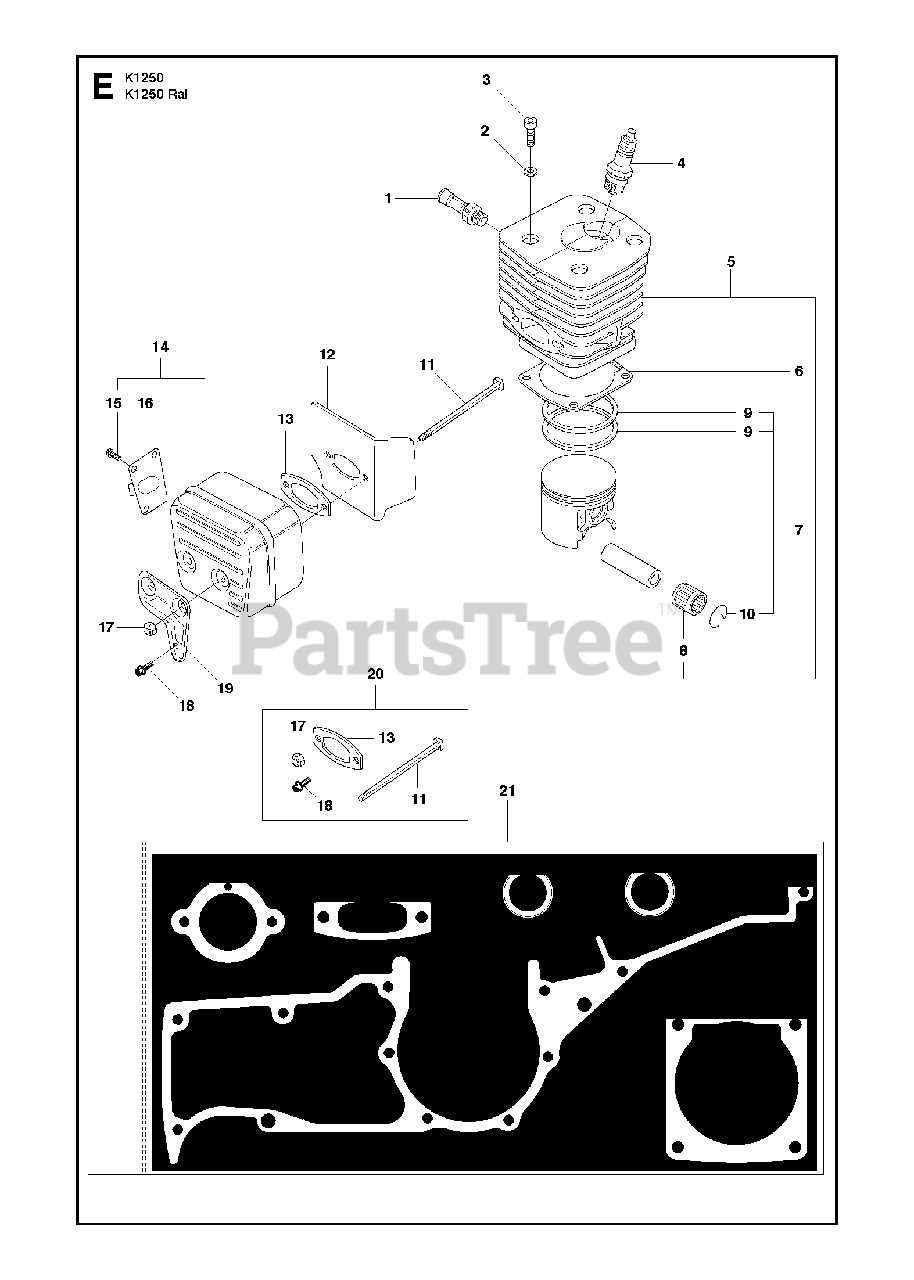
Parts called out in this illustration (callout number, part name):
1	DECOMPRESSION VALVE
5	CYLINDER ASSYIncl. 6 - 8
6	GASKETGasket kit 21
7	PISTON ASSYIncl. 9 - 10
8	NEEDLE HOLDER
12	COOLING AIR CONDUCTOR
13	GASKETGasket kit 21
14	MUFFLER ASSYIncl. 15 - 16
15	SCREW CCRPANT
20	ASSEMBLY KITIncl. 11, 13, 17, 18
21	GASKET KITIncl. 6, 13, 22 - 24
22	GASKET
24	SEALING RING
